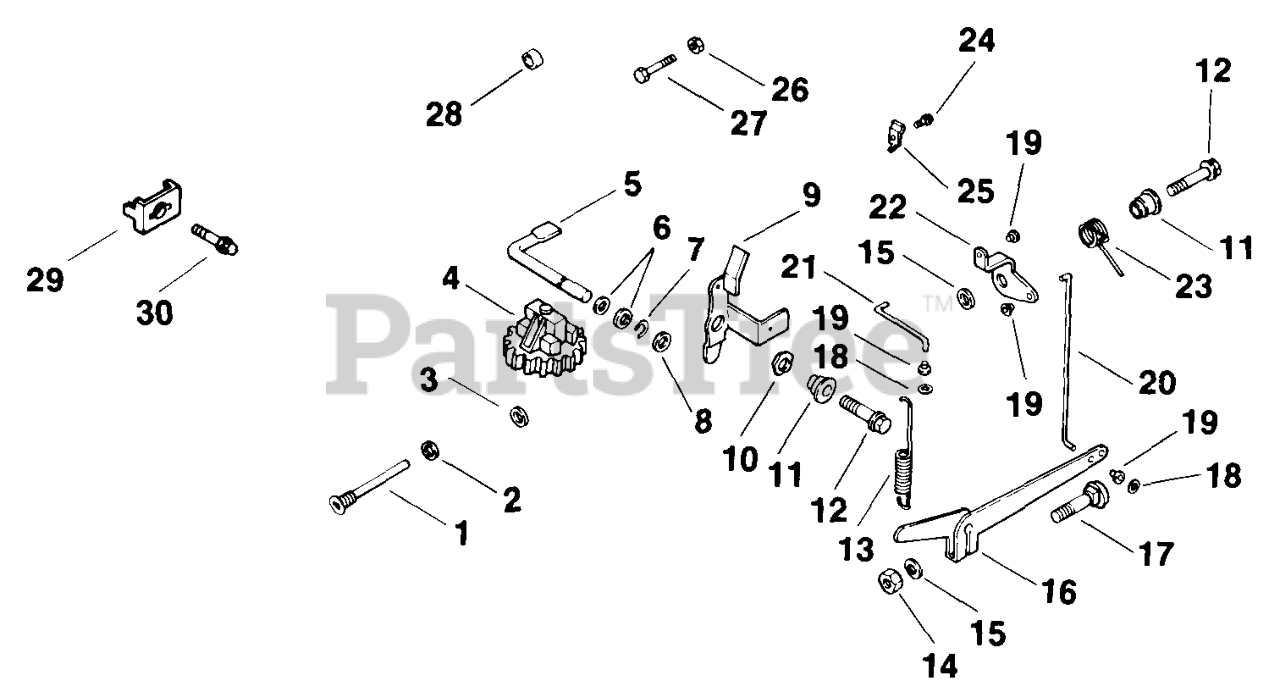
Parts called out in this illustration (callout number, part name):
4	KIT, GOVERNOR GEAR
5	SHAFT - (#DSC)
6	WASHER, FLAT 1/4"
8	WASHER, FLAT 1/4" (O.D. 1/2")
9	LEVER (#DSC)
10	WASHER, SPRING 3/8"
11	BUSHING - DISCONTINUED
12	SCREW, WSH HD 1/4-20X1"
13	SPRING, GOVERNOR
14	NUT, 1/4-20 GRADE 2 USE 25 100 20-S
15	WASHER, FLAT 1/4"
16	ARM - (#DSC)
17	BOLT, RD HD SQ NCK 1/4-20X1"
18	RING, RETAINING - (#DSC)
19	BUSHING, LINKAGE RETAINING
20	LINKAGE - (#DSC)
21	LINK - (#DSC)
22	LEVER - DISCONTINUED
23	SPRING - DISCONTINUED
24	SCREW, WSH HD TAP #10-24X13/32" USE 25 086 109-S
26	NUT, MACH SCREW #10-32 GRD 2 USE 25 100 18-S
27	SCREW, IND HD 10-32X1 3/4" - DISC.
30	SCREW, WSH HD 1/4-20X5/8" - DISCONTINUED
